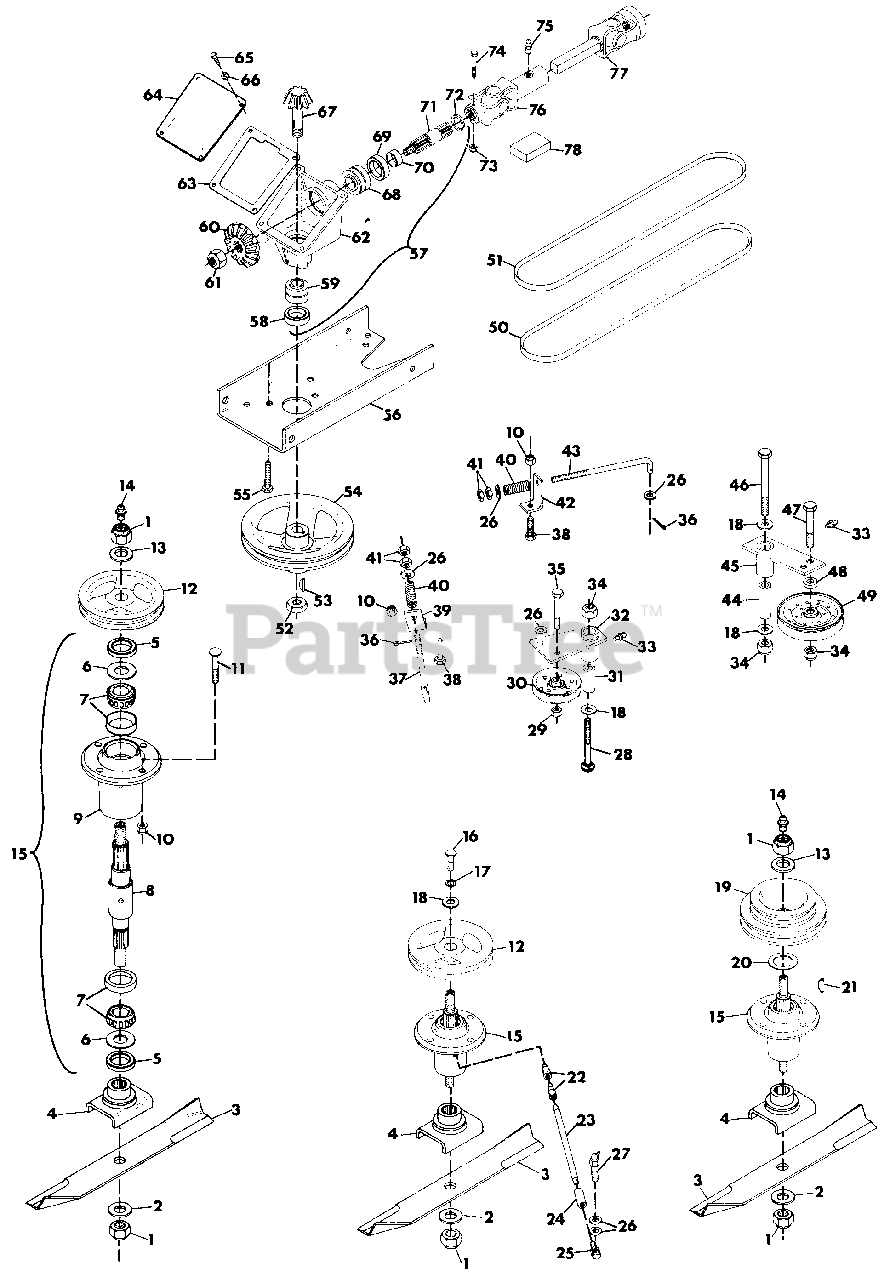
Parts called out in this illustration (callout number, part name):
1	NUT, LOCK 5/8-11
2	WASHER, FLAT .656X1.312X.095
3	BLADE
4	WELDMENT, BLADE CRADLE
5	SEAL, STEEL(RIGHT AND CENTER SPINDLES)
5	SEAL, STEEL(LEFT SPINDLE)
6	WASHER, FLAT .975X1.970X.030(RIGHT ANDCENTER SPINDLES)
6	WASHER, FLAT .975X1.970X.030(LEFT SPINDLE)
7	ASSEMBLY, BEARING CUP AND CONE
8	SHAFT, SPINDLE(RIGHT SPINDLE)
8	SHAFT, SPINDLE(CENTER SPINDLE)
8	SHAFT, SPINDLE(LEFT SPINDLE)
9	HOUSING, BEARING(LEFT AND RIGHT SPINDLES)
9	HOUSING, BEARING(CENTER SPINDLE)
10	NUT, LOCK 3/8-16
11	BOLT, 3/8-16X1.375 RD HD SQ NK
12	PULLEY
13	WASHER, FLAT .687X1.312X.122
14	FITTING, LUBE 1/8
15	ASSEMBLY, SPINDLE(RIGHT)
15	ASSEMBLY, SPINDLE(LEFT)
16	BOLT, HEX SPECIAL 1/2-13X1.34
17	WASHER, LOCK 1/2 REG.
18	WASHER, FLAT .500X1.250X.083
19	PULLEY, DRIVE
20	RACE, BEARING THRUST
21	KEY, WOODRUFF .25X1.00 HARD #15
22	ELBOW, STREET 1/8-26(CENTER SPINDLE)
23	NIPPLE, PIPE 6.30
24	COUPLING, PIPE 1/8-27
25	ELBOW, ADAPTOR 90 DEG.
26	WASHER, FLAT .406X.812X.065
27	FITTING, LUBE 65 DEG.
28	BOLT, 1/2-13X3.5 RD HD SQ NK
29	NUT, LOCK 3/8-16
30	SHEAVE, IDLER
31	SPACER, .850X.546X2.18
32	WELDMENT, IDLER PIVOT
33	FITTING, LUBE 1/4-28
34	NUT, LOCK 1/2-13
35	BOLT, HEX 3/8-16X1.75
36	PIN, COTTER .06X1.000
37	ROD, IDLER
38	BOLT, HEX 3/8-16X1.00
39	SUPPORT, SPRING
40	SPRING, COMP. 1X.78X338
41	NUT, HEX 3/8-24
42	SUPPORT, SPRING
43	ROD, IDLER
44	SPACER, .850X.546X2.50
45	WELDMENT, IDLER PIVOT
46	BOLT, HEX 1/2-13X3.75
47	BOLT, HEX 1/2-13X2.00
48	SPACER, .516X.875X.300
49	PULLEY, FLAT IDLER
50	BELT, "B"
51	BELT, "A"
52	NUT, JAM 3/4-10 HEX HEAVY
53	KEY, WOODRUFF 3/16X5/8 NO. 61
54	PULLEY, GEAR BOX
55	BOLT, HEX 1/2-13X1.00
56	PLATE, SUPPORT
57	ASSEMBLY, DRIVE
58	SEAL, OIL
59	ASSEMBLY, BEARING
60	GEAR, BEVEL
61	NUT, LOCK 3/4-10
62	CASTING, GEAR BOX
63	GASKET, GEAR HOUSING
64	COVER, GEAR HOUSING
65	BOLT, HEX 1/4-20X.50
66	WASHER, LOCK 1/4 REG.
67	SHAFT, GEAR PINION
68	ASSEMBLY, BEARING
69	SEAL, OIL
70	SPACER
71	SHAFT
72	RING, RETAINING 1.000 SHAFT
73	NUT, LOCK 1/4-20
74	BOLT, HEX 1/4-20X2.25
75	FITTING, LUBE 1/4-28
76	U-JOINT, FEMALE
77	SHAFT, PROP. SQ. BAR
78	KIT, REPAIR U-JOINT
